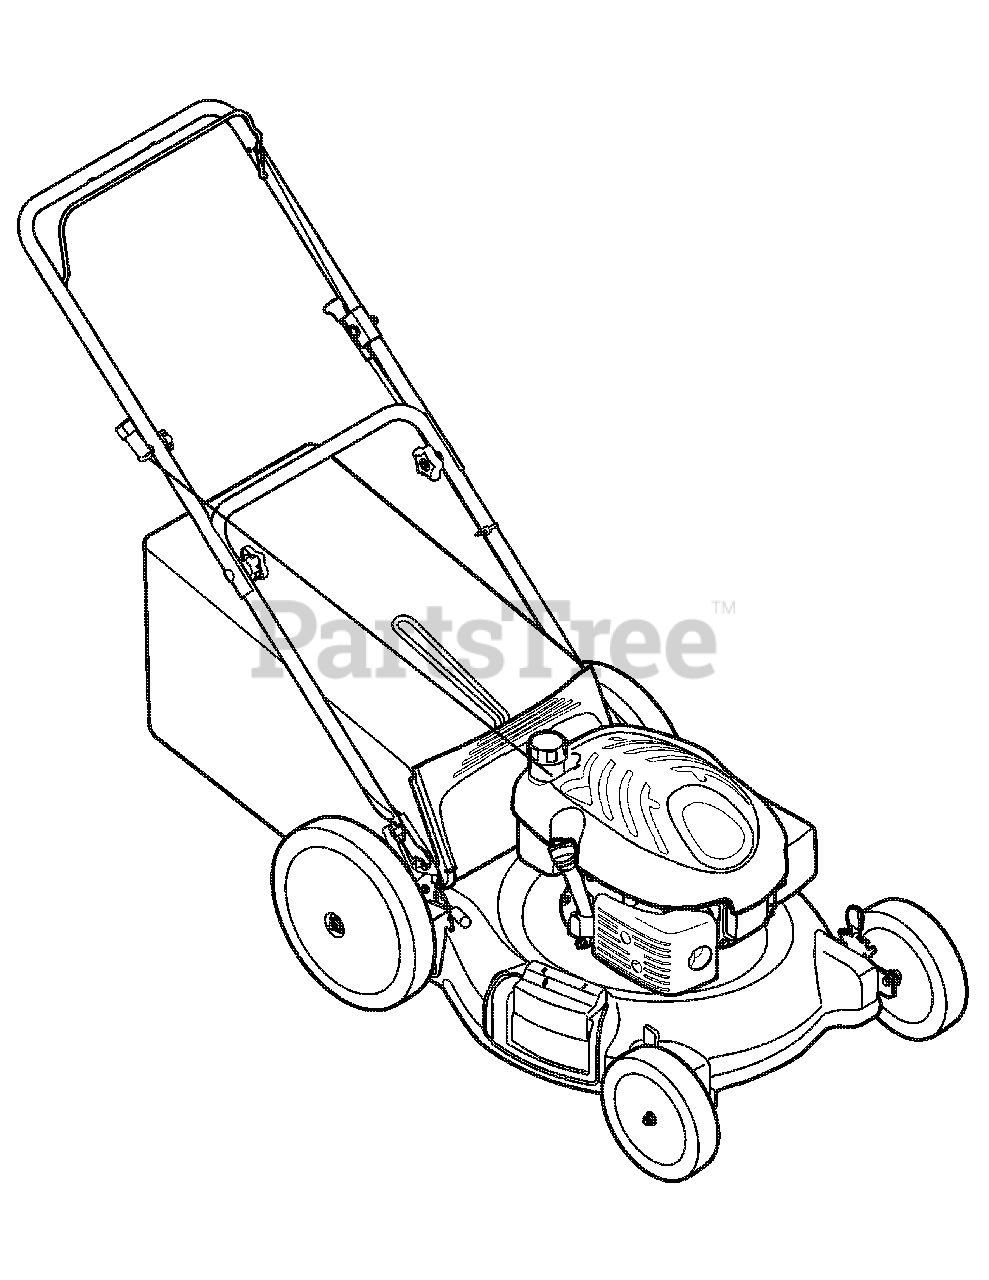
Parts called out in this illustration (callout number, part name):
NA	Pre-Filter
NA	Drive Belt
NA	Drive Cable
NA	Ignition Key
